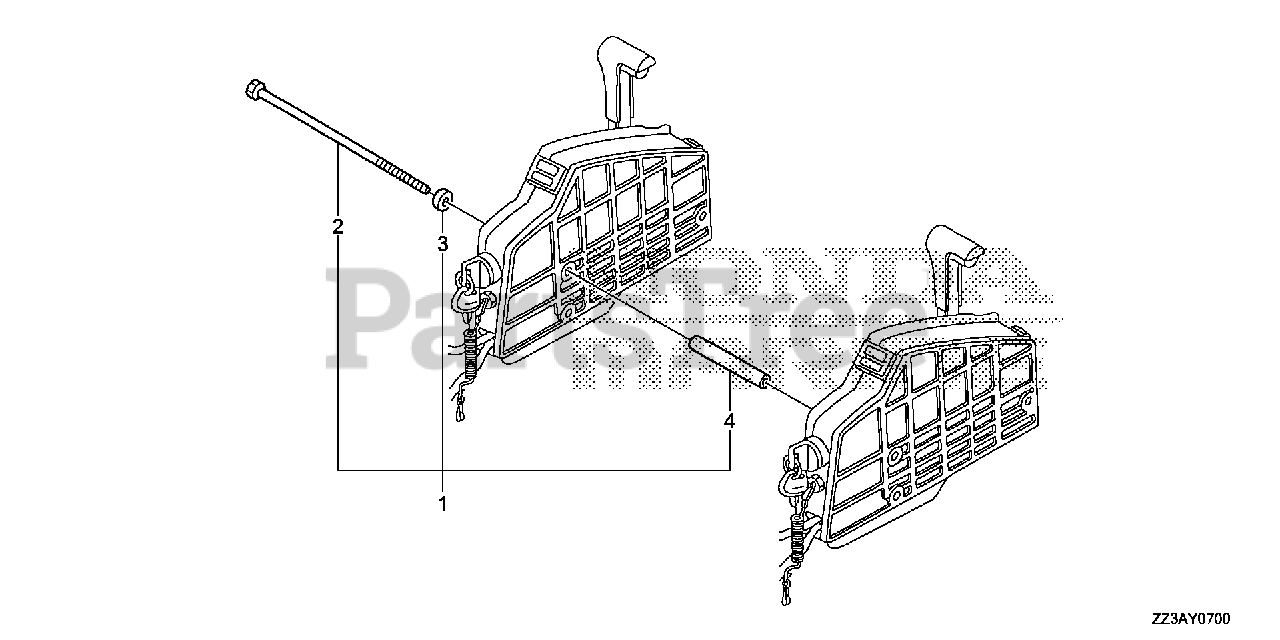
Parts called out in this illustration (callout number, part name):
1	BOLT KIT, SIDE REMOTE CONTROL
2	BOLT, SPECIAL (6X220)
3	COLLAR, DISTANCE (A)
4	COLLAR, DISTANCE (B)
